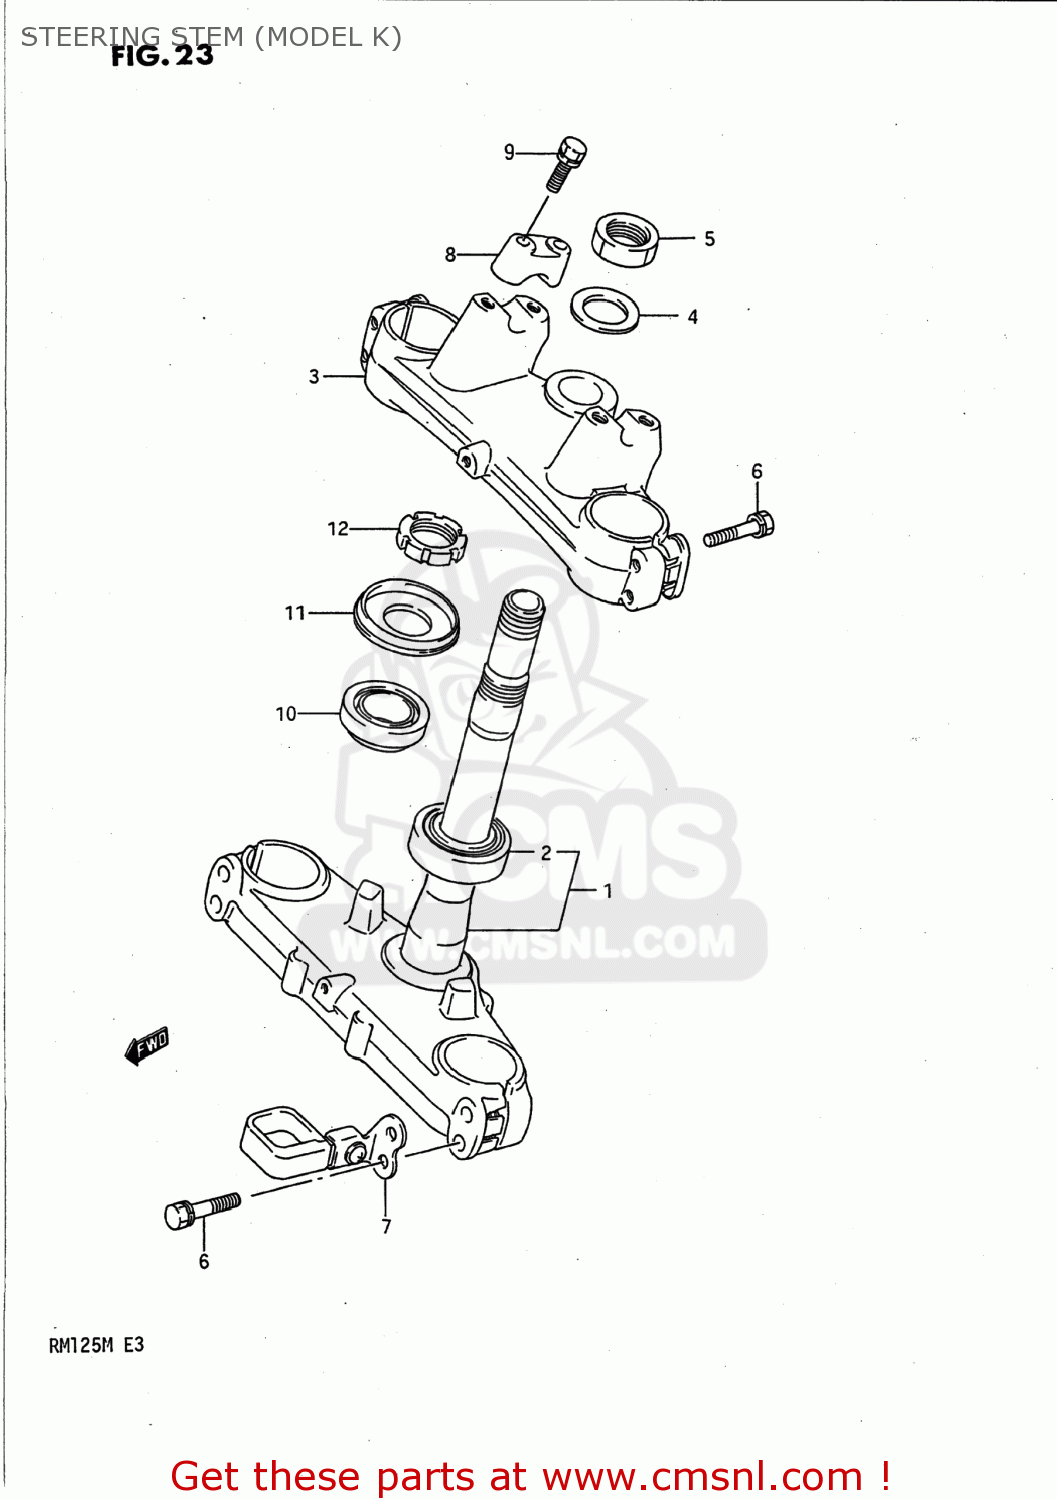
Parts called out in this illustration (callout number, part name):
1	STEM,STEERING
2	BEARING(28X54X16)
3	STEM HEAD,STEERING
4	WASHER,STEM HEAD(24.5X34X1.6)
5	NUT,STEM HEAD
6	BOLT
7	GUIDE,HOSE
8	HOLDER,HANDLEBAR
9	BOLT,HANDLE HOLDER
10	BEARING
11	SEAL,STEERING,UPPER DUST
12	NUT,STEERING
